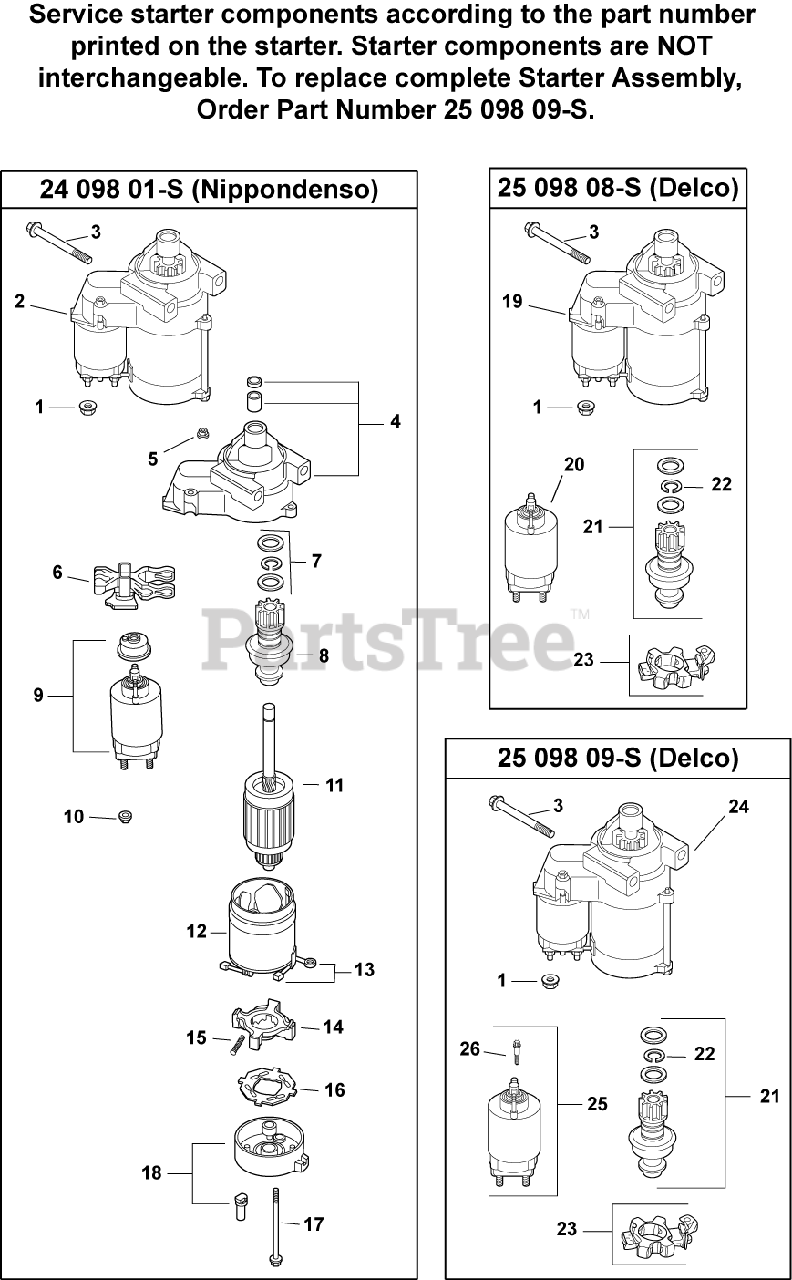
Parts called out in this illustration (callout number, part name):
1	NUT, FLG M8X1.25
3	SCREW, FLG M8X1.25X80
4	DRIVE, END CAP
6	LEVER, DRIVE
7	KIT, STARTER REPAIR
8	DRIVE PINION
11	ARMATURE - (#DSC)
12	FRAME W/BRUSHES - DISCONTINUED
13	BRUSH HOLDER
14	BRUSH & SPRING KIT
15	SPRING, BRUSH
16	INSULATOR
17	THRU BOLT
18	COMMUTATOR, END CAP - DISCONTINUED
19	STARTER, SOLENOID SHIFT-USE 25 098 11-S
21	KIT, STARTER PINION
22	RING, RETAINING
23	KIT, BRUSH HOLDER
24	STARTER, SOLENOID SHIFT-USE 25 098 11-S
25	KIT, SOLENOID
26	SCREW, EXTERNAL TORX HEAD
